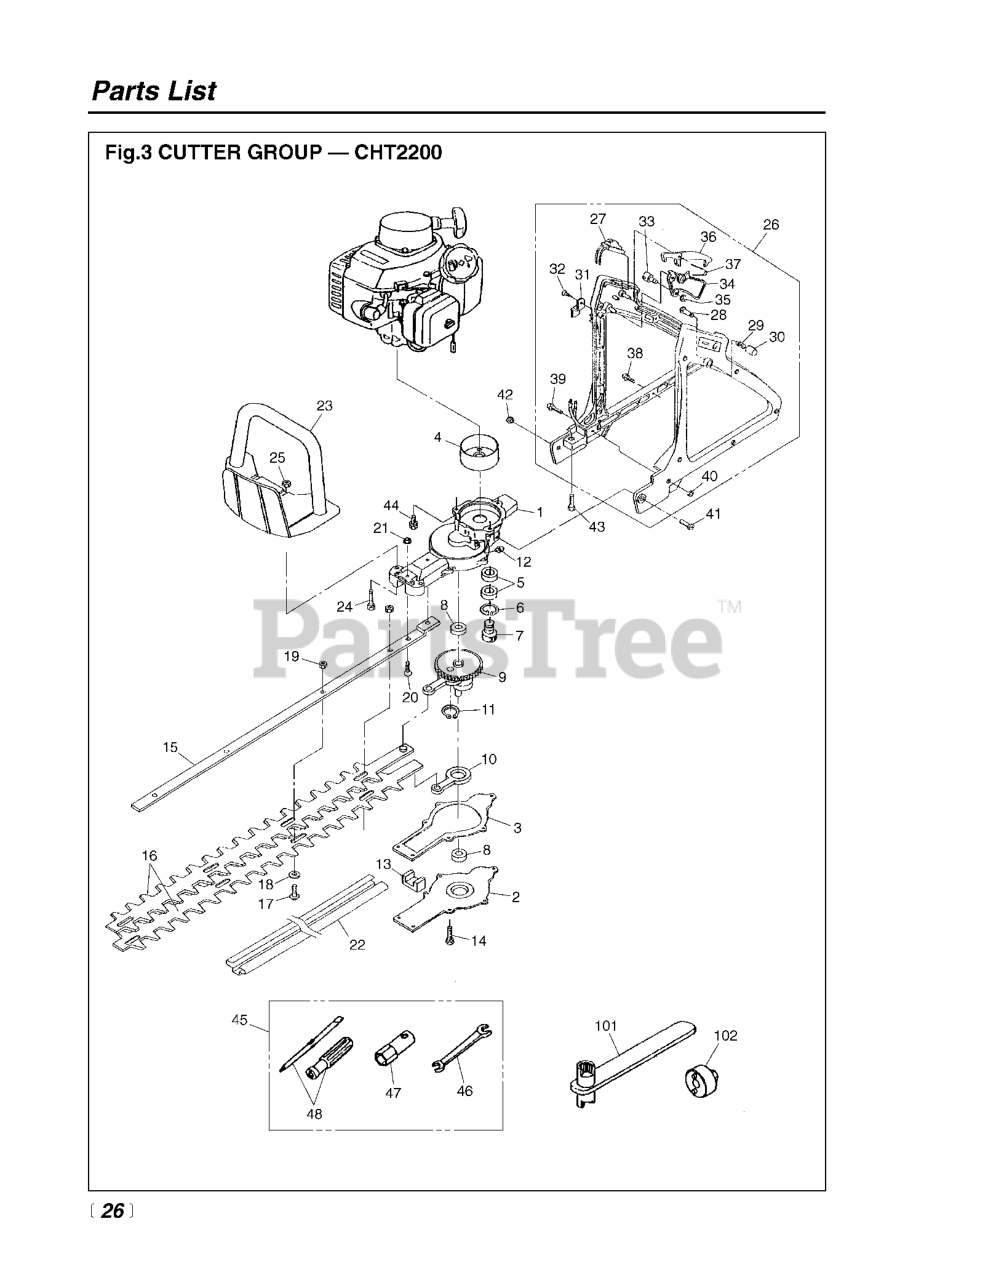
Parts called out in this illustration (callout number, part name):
1	GEARCASE
6	RING, SNAP
8	BEARING
9	GEAR COMPL
11	RING, SNAP, M25 x 1.2
14	BOLT (RPLS 020510512)
15	PLATE, GUIDE
16	BLADE (22")
17	SCREW
22	COVER, BLADE
23	HANDLE, FRONT
26	HANDLE.REAR-A
27	SWITCH-A
33	WIRE END
45	TOOL SET
101	WRENCH(B)
